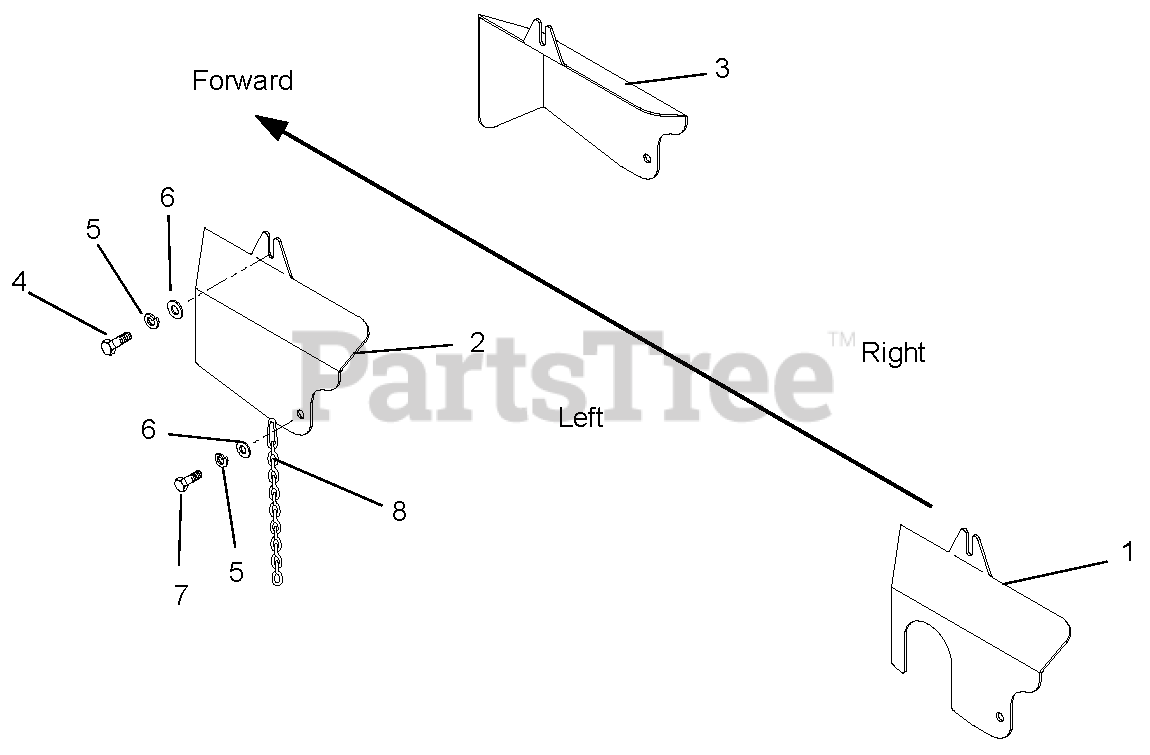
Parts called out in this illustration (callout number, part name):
1	Weldment, Belt Guard Center Rear (Unit #1)
2	Weldment, Belt Guard Outside Left (Unit #2)
3	Weldment, Belt Guard Outside Right (Unit #3)
4	Cap Screw, Hex Head .312 x .75
5	Washer, Lock .312
6	Washer, Flat .312
7	Cap Screw .312-18 x 1.25
8	Chain, Safety
